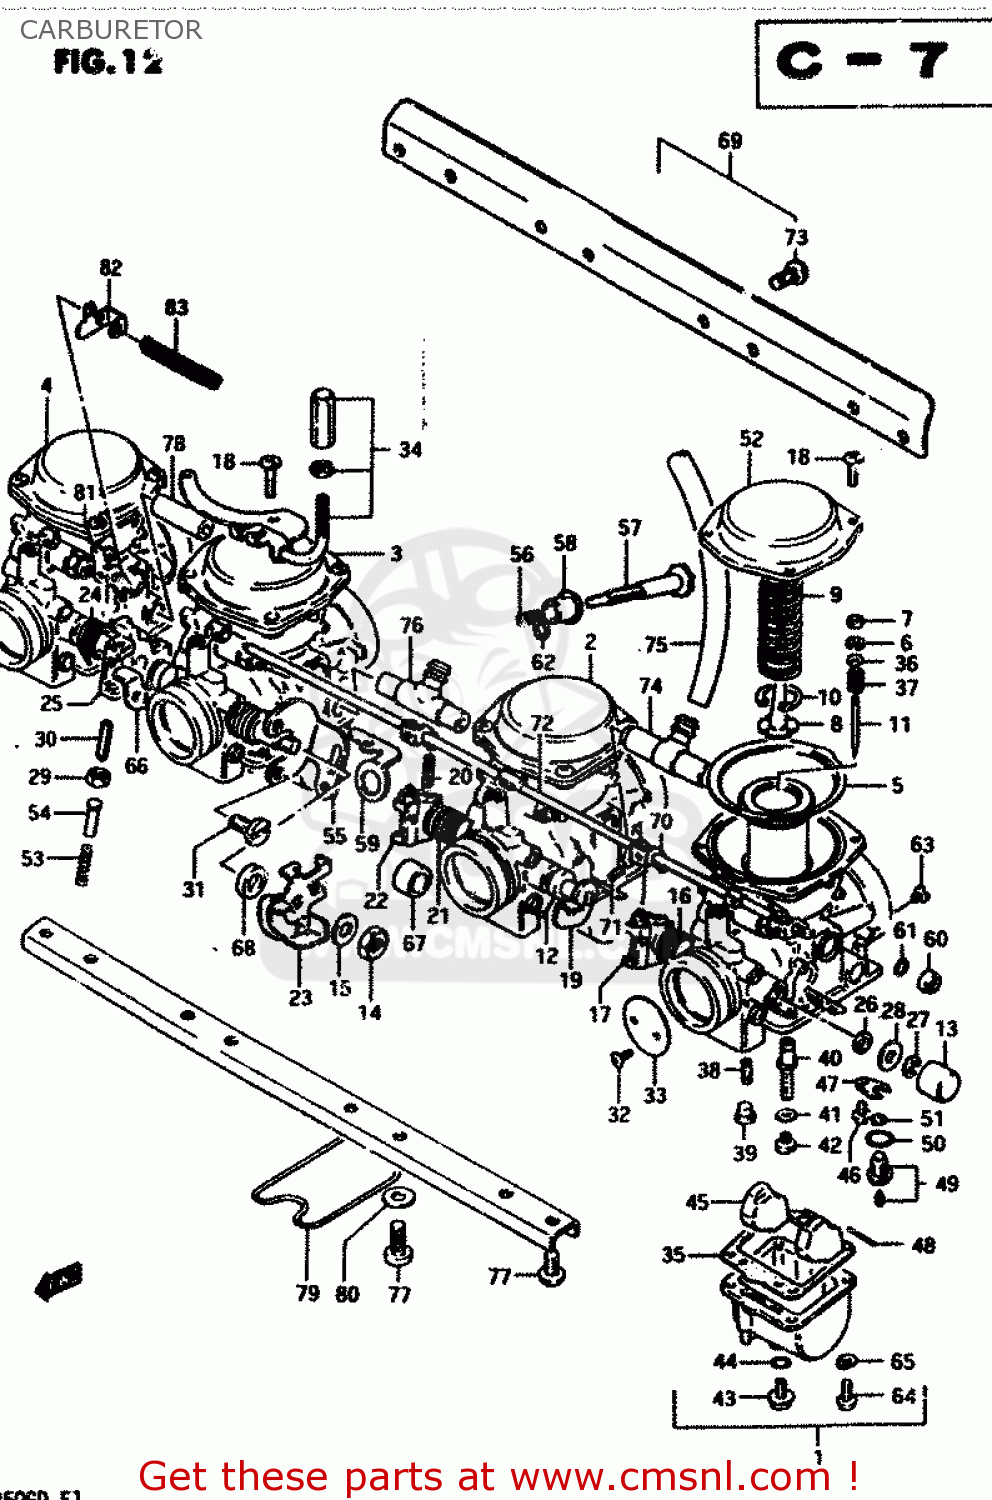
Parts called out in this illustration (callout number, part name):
1	CARBURETOR, NO.1
2	CARBURETOR, NO.2
3	CARBURETOR, NO.3
4	CARBURETOR, NO.4
5	DIAPHRAGM
6	CLIP,NEEDLE
7	RING
8	HOLDER,GUIDE
9	SPRING
10	E RING
11	NEEDLE, JET (5057-2)
12	GASKET,THROTTLE SHAFT (NAS)
13	CAP
14	NUT
15	WASHER
16	SPRING,THROTTLE SHAFT
17	SHAFT,THROTTLE
18	SCREW
19	SHAFT ASSEMBLY
20	PIN,THROTTLE SHAFT
21	SPRING,THROTTLE SHAFT
22	LEVER,THROTTLE SHAFT
23	LEVER ASSEMBLY,THROTTLE
24	SPRING,THROTTLE SHAFT
25	SHAFT,THROTTLE
26	SEAL
27	E RING
28	GASKET,THROTTLE SHAFT (NAS)
29	NUT
30	SCREW
31	SCREW
32	SCREW
33	VALVE,THROTTLE
34	BRACKET,THROTTLE CABLE
35	GASKET,FLOAT CHAMBER (NAS)
36	WASHER
37	SPRING
38	JET, PILOT (42.5)
39	PLUG,NEEDLE JET
40	JET, NEEDLE (X-6)
41	WASHER,NEEDLE NOZZLE
42	JET,MAIN(115)
43	PLUG,DRAIN
44	GASKET (NAS)
45	FLOAT
46	SCREW 4X6
47	PLATE,NEEDLE VALVE FITING
48	PIN,FLOAT
49	VALVE ASSEMBLY,NEEDLE
50	O-RING,NEEDLE VALVE
51	FILTER
52	COVER,DIAPHRAGM
53	SPRING,THROTTLE SCREW
54	PIN,THROTTLE LEVER
55	BRACKET,THROTTLE ADJUST
56	SPRING
57	SCREW
58	BUSH
59	BRACKET,THROTTLE ADJUST
60	CAP,STARTER VALVE
61	O RING
62	WASHER
63	JET,AIR
64	SCREW
65	LOCK WASHER
66	SHAFT ASSEMBLY
67	RING
68	RING
69	CARBURETOR ASSEMBLY
70	LEVER
71	SCREW
72	SHAFT,STARTER
73	SCREW
74	NIPPLE
75	HOSE,CARBURETOR
76	NIPPLE
77	SCREW 6X12
78	NIPPLE
79	CLAMP
80	WASHER
81	LEVER,CHOKE CABLE
82	PLATE,CHOKE CABLE
83	SPRING,CHOKE CABLE
